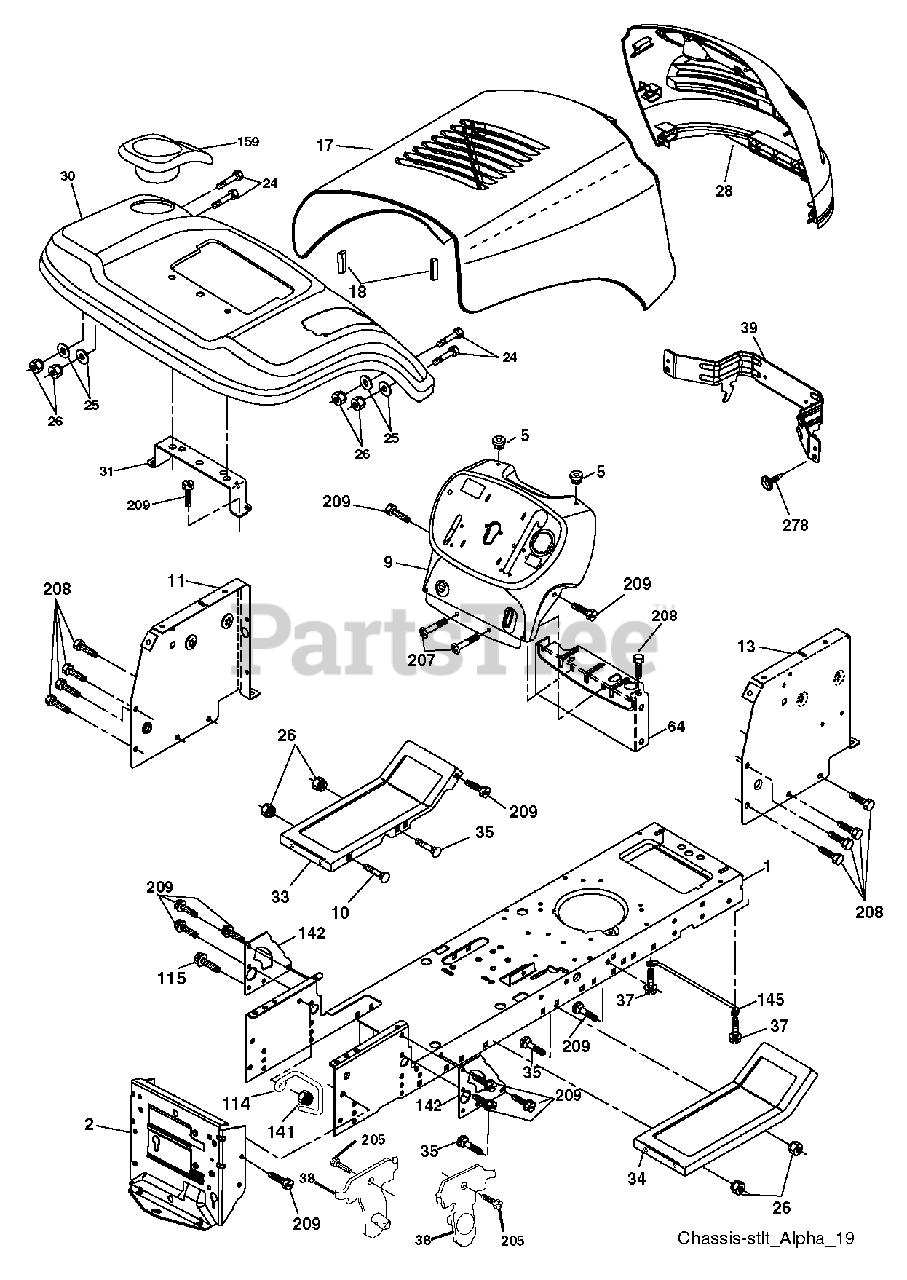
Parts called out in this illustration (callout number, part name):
1	CHASSIS STAMPING
2	DRAWBAR, 12GA
5	BUMPER.RUBBER.HOOD
11	PANEL.DASH.LH.LTX
17	HOOD.PNT.STEEL.ALPHA.LT.667
18	BUMPER.HOOD.LARGE.1.75"
25	WASHER
26	NUT
28	GRILL.ALPH.N/LTS.W/POUL.DEC667
30	FENDER.PNT.LIST.W/SFT.W/CUP.HD
31	BRACKET FENDER
33	FOOTREST.PNT.LH.MS667
34	FOOTREST.PNT.RH.MS667
37	SCREW LT
38	BRACKET.ASM.PIVOT.MOWER.REAR
39	BRACKET.PIVOT.ALPHA.LT
64	DASH LOWER
115	SCREW.3/8-16
141	NUT LOCK FLG 3/8-16 UNC
142	PLATE REINFORCEMENT
145	ROD.PIVOT.HOOD
159	CUPHOLDER.BLACK
205	SCREW LT
207	SCREW, 5/16-18 X 1/2
208	SCREW 3/8-16X1/2
209	SCREW, 3/8-16X3/4
278	SCREW.#10 X 0.750.BOS (2 2)
